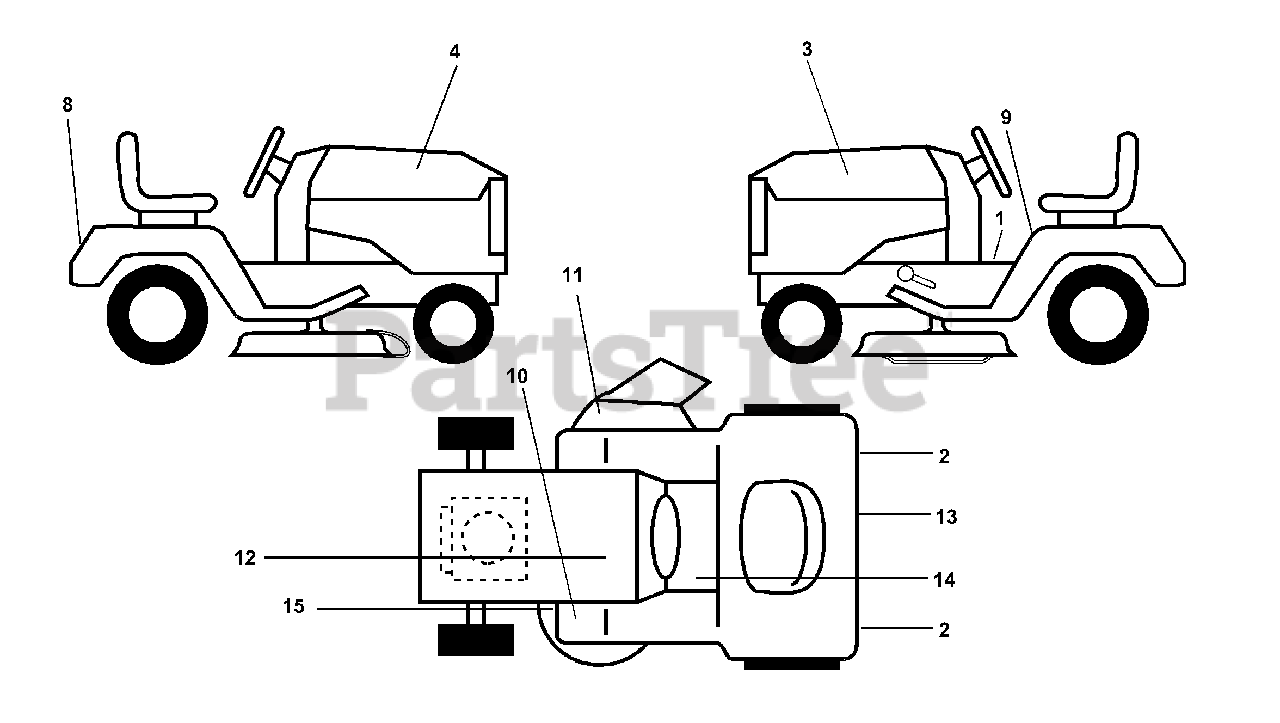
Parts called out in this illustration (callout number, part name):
1	Decal Instruction Dash Eng/fr
2	Reflector Tail Light Red/amber
3	Decal Hood LH Husq P/L YTH180
4	Decal Hood RH Husq P/L YTH180
8	Decal Fender Logo Husq
9	Decal Caution Fender Eng/fr
10	Decal Clutch/brake Eng/fr
11	Decal Warning Multi-Language
12	Decal Bat Dan/Poi P/L Sym WAC
13	Decal Drawbar CNTRL MVT HYD LT
14	Decal SDL COLD START HYD E/F
15	Decal V-Belt Schematic 44" 46" 50" Vented
